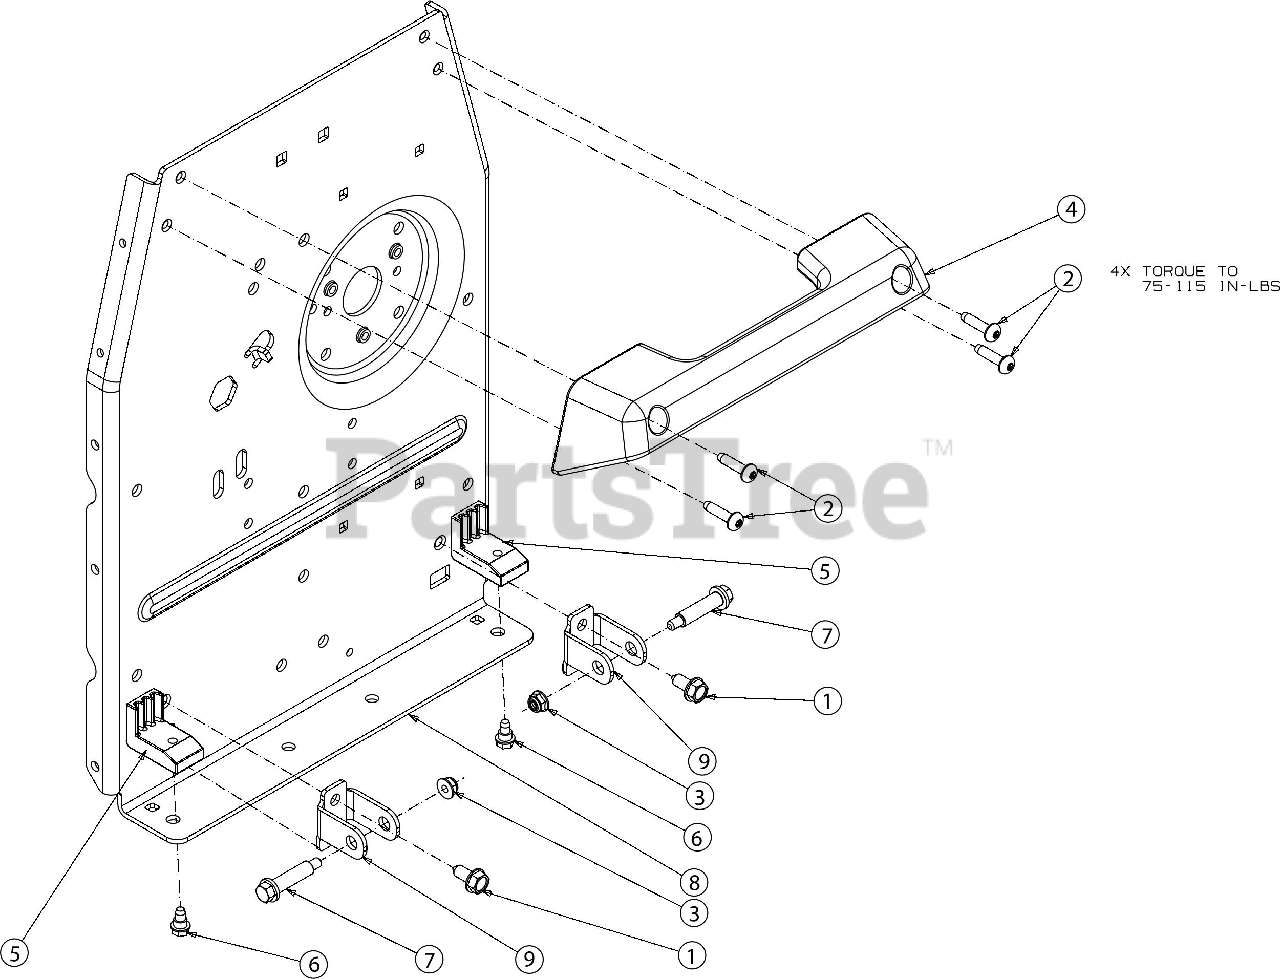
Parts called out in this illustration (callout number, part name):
1	SCREW 5/16-18 x .750
2	SCREW 1/4-20 x 1.0
3	FLANGE LOCK NUT
5	BUMPER PAD
6	SHOULDER SCREW 1/4-20 x .50
7	SHOULDER SCREW
8	FRAME MOUNT BRACKET
9	SUPPORT BRACKET
